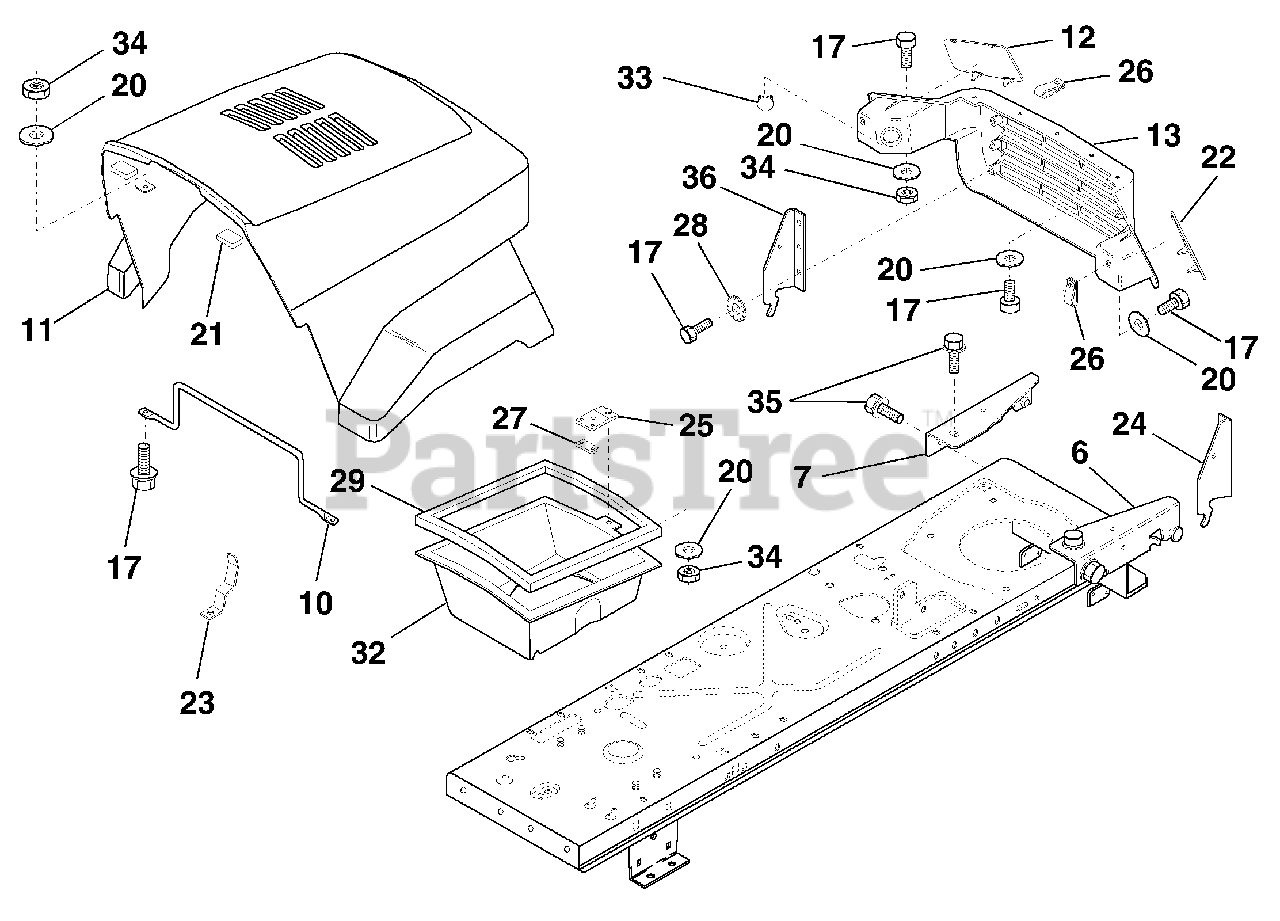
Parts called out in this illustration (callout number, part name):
6	Bracket Asm. Pivot Hood RH
7	Bracket Asm. Pivot Hood LH
10	Brace Hood
11	Hood
12	Lens LH
13	Grille
17	Bolt Fin Hex 1/4-20 x 5/8
20	Washer, Flat 1/4
21	Bumper Hood
22	Lens RH
23	Latch Hood
24	Bracket Pivot Hood RH
25	Clip Tinnerman
26	Clip Tinnerman
27	Clip Asm Duct
28	Washer Lock Ext. Tooth
29	Strip Foam
32	Duct, Air Hood
33	Plug Socket Light
34	Nut, Crownlock 1/4-20
35	Screw Thdrol 5/16-28 x 3/4
36	Bracket Pivot Hood LH
